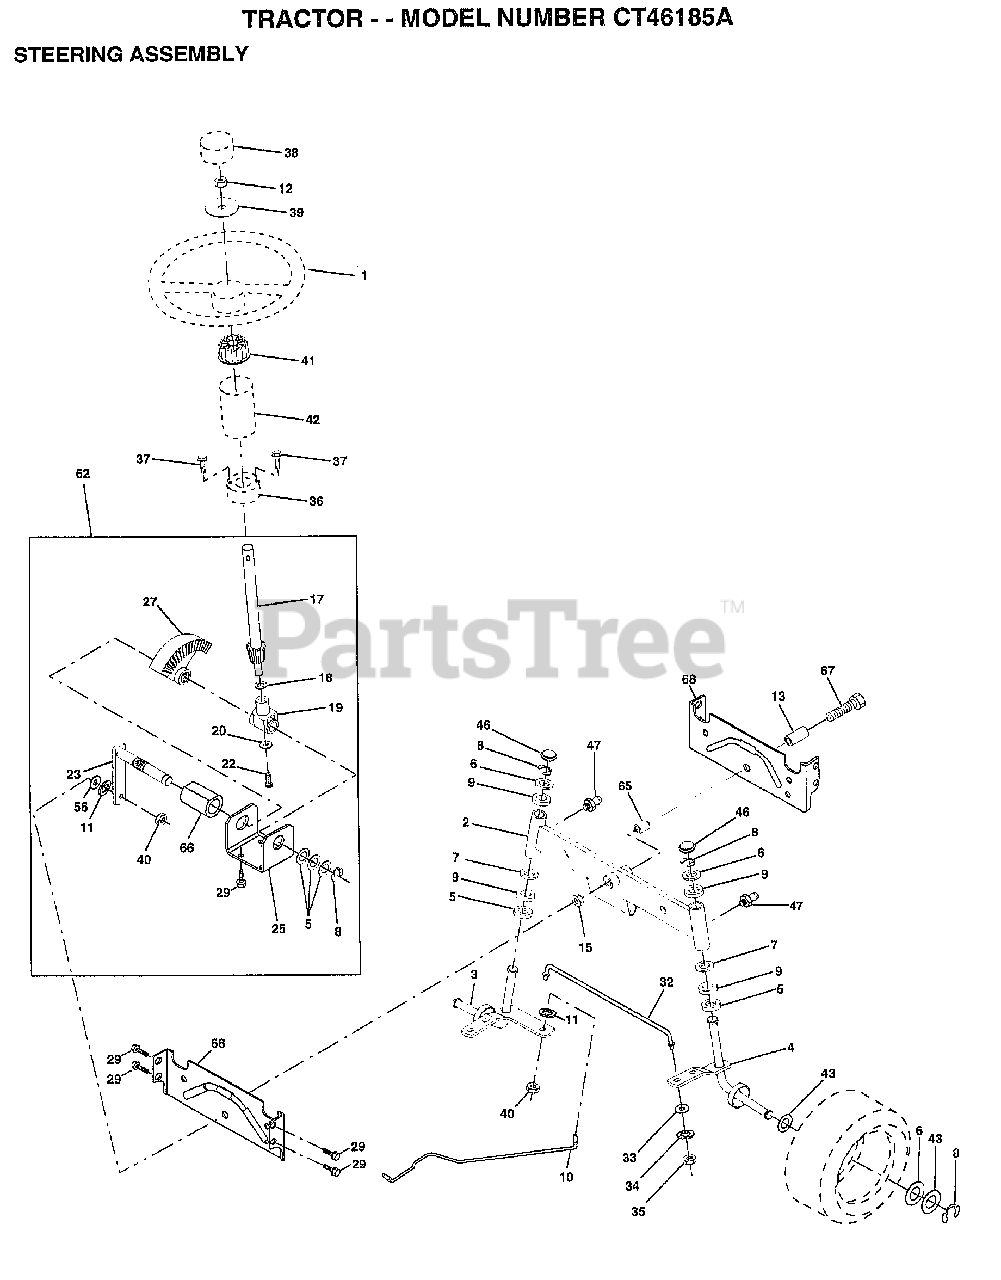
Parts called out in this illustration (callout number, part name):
1	WHEEL STR AYP BLK
2	AXLE ASM
3	"SPINDLE ASM,RH"
4	"SPINDLE AMS,LH"
5	WASHER .T
6	WASHER
7	WASHER
8	RING
9	COL. SRTG. BEAR.
10	DRAGLINK-STAMPED
11	LOCKWASHER
13	BEARING AXLE
15	"NUT-LOC,FLANGE LT"
17	SHAFT ASM STEERNG
18	THRUST WASHER
19	SUPPORT.SHAFT
22	SCREW HEX SOC1/4-
25	BRKT-STEERING
27	GEAR SECTOR
29	SCREW
32	ROD.TIE.19.75
33	WASHER M
34	LOCKWASHER
35	NUT.LOCK.5/16-24
36	BUSHING.STRG.3/4
37	"SCREW-TT,10-32 FL"
38	CAP STEER AYP
39	WASHER
40	GRIPCO NUT
41	ADAPTER LT
42	BOOT SHAFT STEER
43	WASHER
46	CAP
47	ZERK M
56	WASHER
62	KIT STEERING ASM
65	SPACER AXLE
66	"BEARING-ARM,PITMA"
67	BOLT
68	BRACE AXLE
